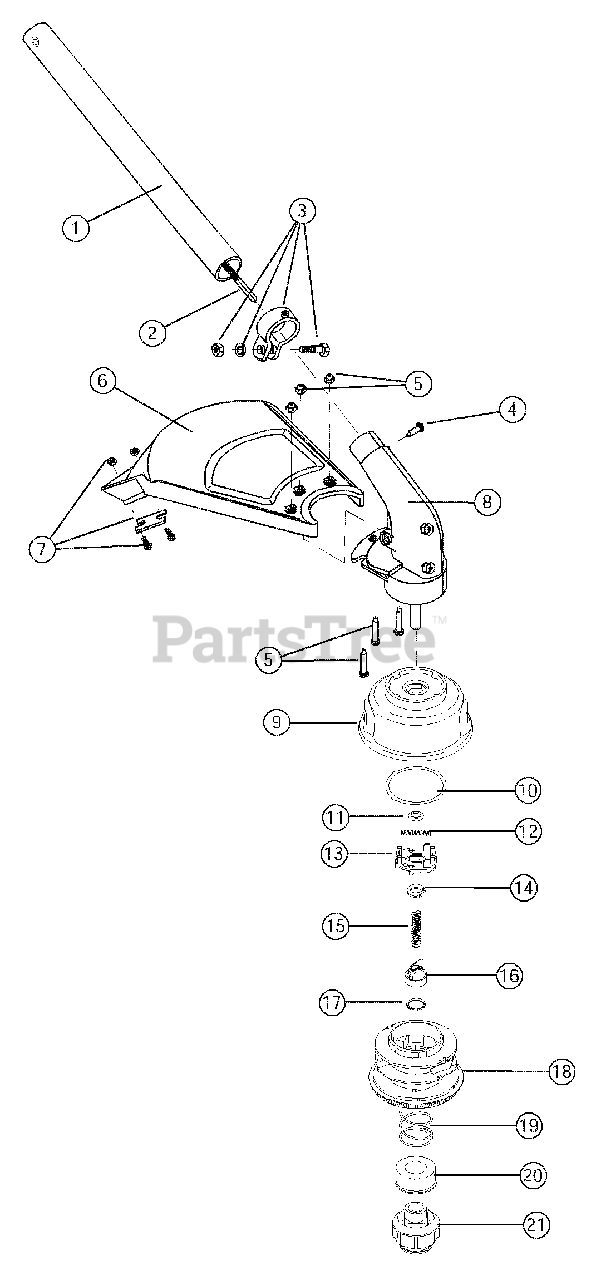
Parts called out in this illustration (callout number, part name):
1	Lower Drive Shaft Housing Assembly
2	Lower Flexible Drive Shaft
3	Lower Clamp Assembly
4	Anti-Rotation Screw
5	Shield Mounting Hardware
6	Shield Assembly
7	Blade Assembly
8	Gearbox Assembly
9	Outer Spool Assembly
10	Thrust Washer
11	Retaining Ring
12	Small Spring
13	Slider
16	Plunger
18	Inner Reel
19	Large Spring
20	Foam Seal
21	Bump Head Knob Assembly
